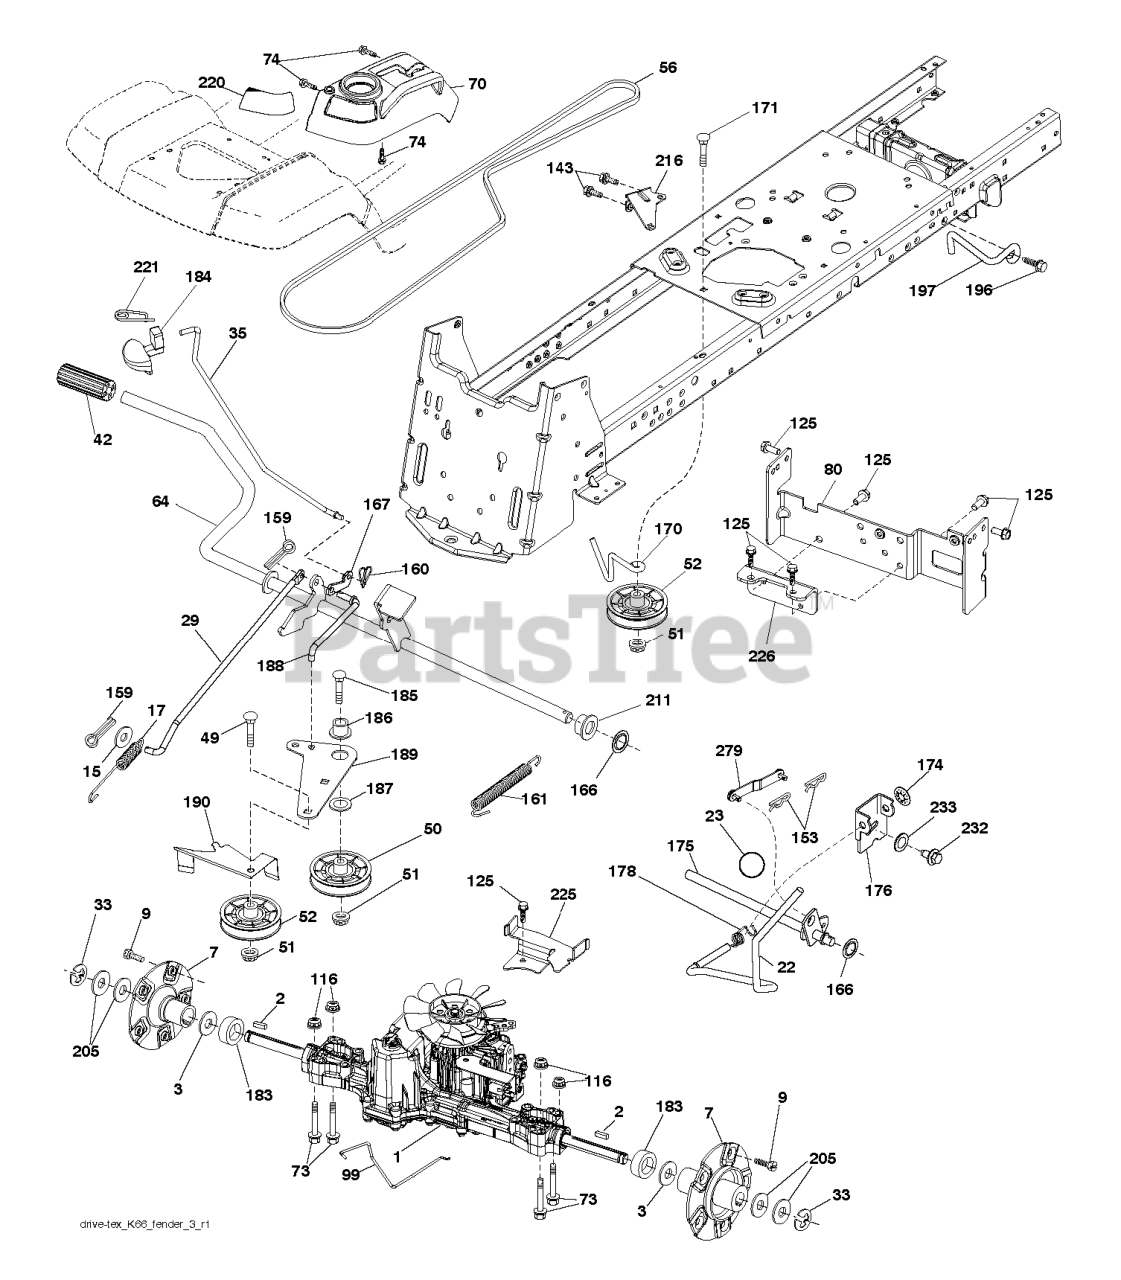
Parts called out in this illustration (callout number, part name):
2	KEY 1/4 X 2.5
7	HUB.ASM.WHEEL.REAR.23"TEX
9	HUB BOLT
15	WASHER
17	SPRING.BRAKE.K46
22	ROD.SHIFT.FENDER.STGT.
23	KNOB.DELUXE.(PISTOL.GRIP).BLAC
29	ROD.BRAKE.K66
33	E RING HYT
35	ROD.BRAKE.PARTK.HUSQ.TEX
42	PEDAL COVER T
50	IDLER.FLAT.910.OFFSET
51	NUT LOCK FLG 3/8-16 UNC
52	IDLER.V-GROOVE.910.OFFSET
64	SHAFT.ASM.PEDAL.BRAKE.
70	SUBASM.CONSOLE.HUSQ.GT.HYDRO
73	BOLT HEX 5/16-18 GR 5
74	SCREW.HI-LO.CONSOLE
80	STRAP.TORQUE.K66
99	ROD.SPRING.BYPASS.K66.GT.Z
116	NUT LOCK HEX FLANGE 5/16-18
125	SCREW
143	SCREW LT
153	RETAINER M
159	COTTER PIN
160	RETAINER CLIP
161	SPRING, RETURN LT
166	NUT.PUSH.625
167	LATCH.BRAKE.SPRING
170	KEEPER.V-IDLER.CENTER.
171	BOLT
174	NUT.PUSH.500.2006
175	SHAFT.ASM.SHFT.T2.TLT
176	ARM.CLEVIS.ROD.SHIFT
178	SPRING.SHIFT.GT2006
183	SPACER.AXLE.HG.TEX
184	RB HANDLE.PARKG.BRK.HUS/PRED
186	SPACER.RETAINER
187	WASHER 12/32X2X10GA
188	RP.LINK.CLUTCH.GROUND.DRIVE
189	BELLCRANK.GROUND.DRIVE.TEX.
190	KEEPER.BELLCRANK.DRIVE
196	SCREW 3/8-16X1
197	BRKT.ANIT-ROTATION.CLUTCH
211	BUSHING.SHAFT.BRAKE.HAND
216	BRACKET.PULLEY.IDLER.W/TEX
220	REFLECTOR.RH.TEX GT
221	RETAINER.SPRING.CLIP.H
225	KEEPER.BELT.TRANSAXLE.K66
226	BRACKET.MOUNT.TORQUE.K66.TG
232	BOLT FIN HEX 7/16-14 X 1
233	WASHER SERRATED
279	LINK.ASM.SHIFT.FENDER.K66
